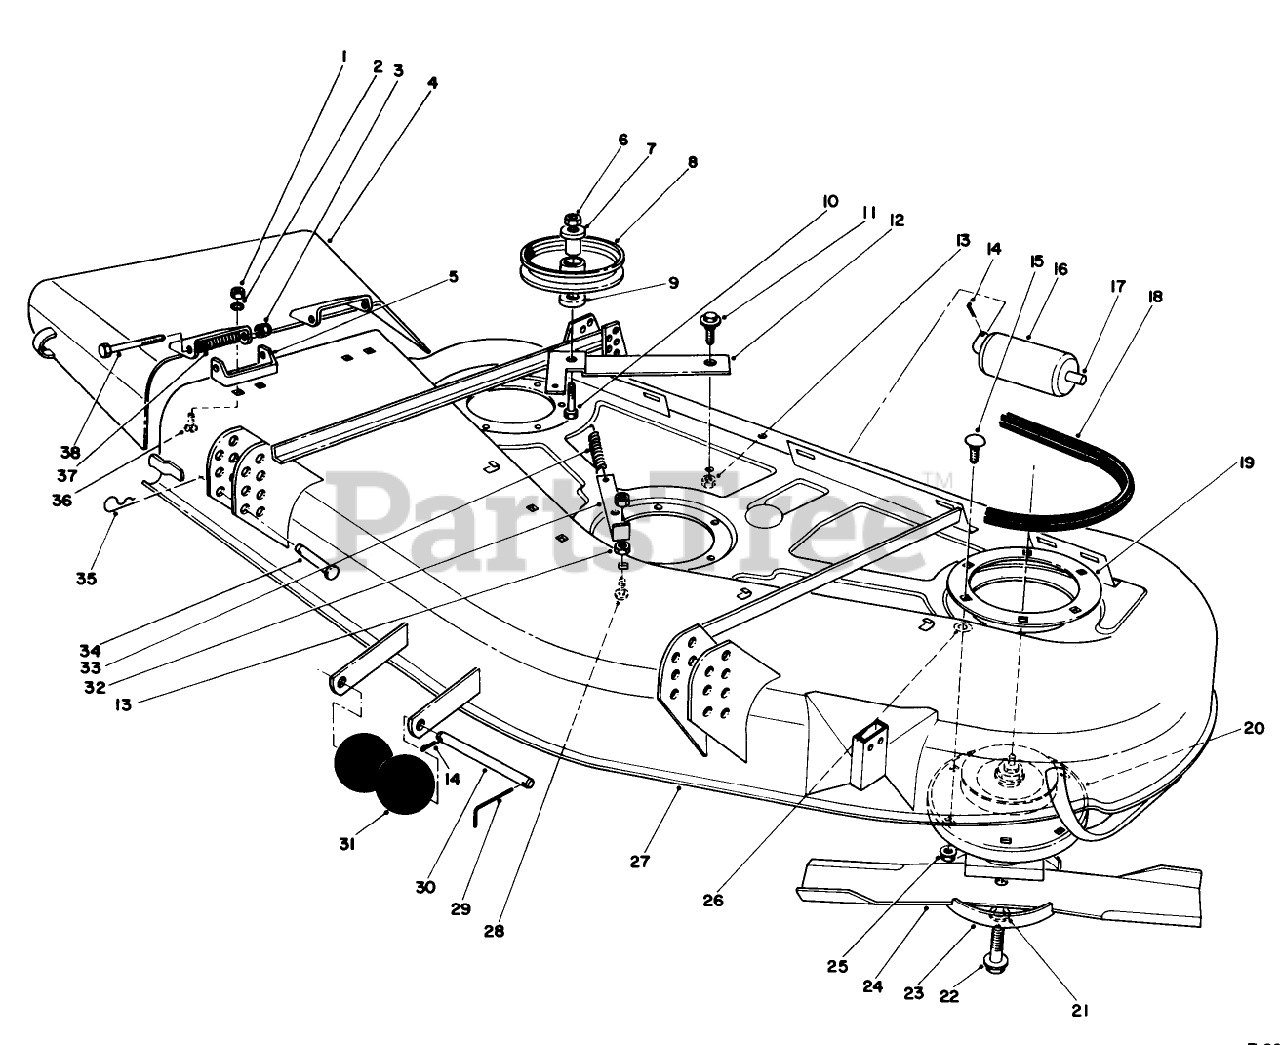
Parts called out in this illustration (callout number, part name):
1	NUT-HEX
2	WASHER-LOCK
3	NUT-HEX
4	DEFLECTOR W/DECALS
5	Bracket-Pivot
6	NUT-HEX
7	BUSHING-PULLEY
8	PULLEY-IDLER
9	WASHER-FLAT
10	SCREW-HH
11	SCREW-SHOULDER
12	Lever-Deck
13	NUT-LOCK, NI
14	PIN-COTTER
15	SCREW-CARR
16	ROLLER-DECK
17	SHAFT-ROLLER, REAR
18	V-BELT, DECK
19	SUPPORT-DECK, RING
20	SPINDLE HSG ASM
21	WASHER-LOCK
22	SCREW-BLADE
23	CUP-SCALP, ANTI
24	Blade
25	NUT-HF
26	WASHER-FLAT
27	Housing
28	SCREW-CARR
29	PIN-SPECIAL
30	SHAFT-ROLLER
31	ROLLER
32	Anchor-Spring
33	SPRING-EXTENSION, DECK
34	PIN-CLEVIS
35	PIN-HAIR
36	SCREW-CARR
37	SPRING
38	SCREW-HH
